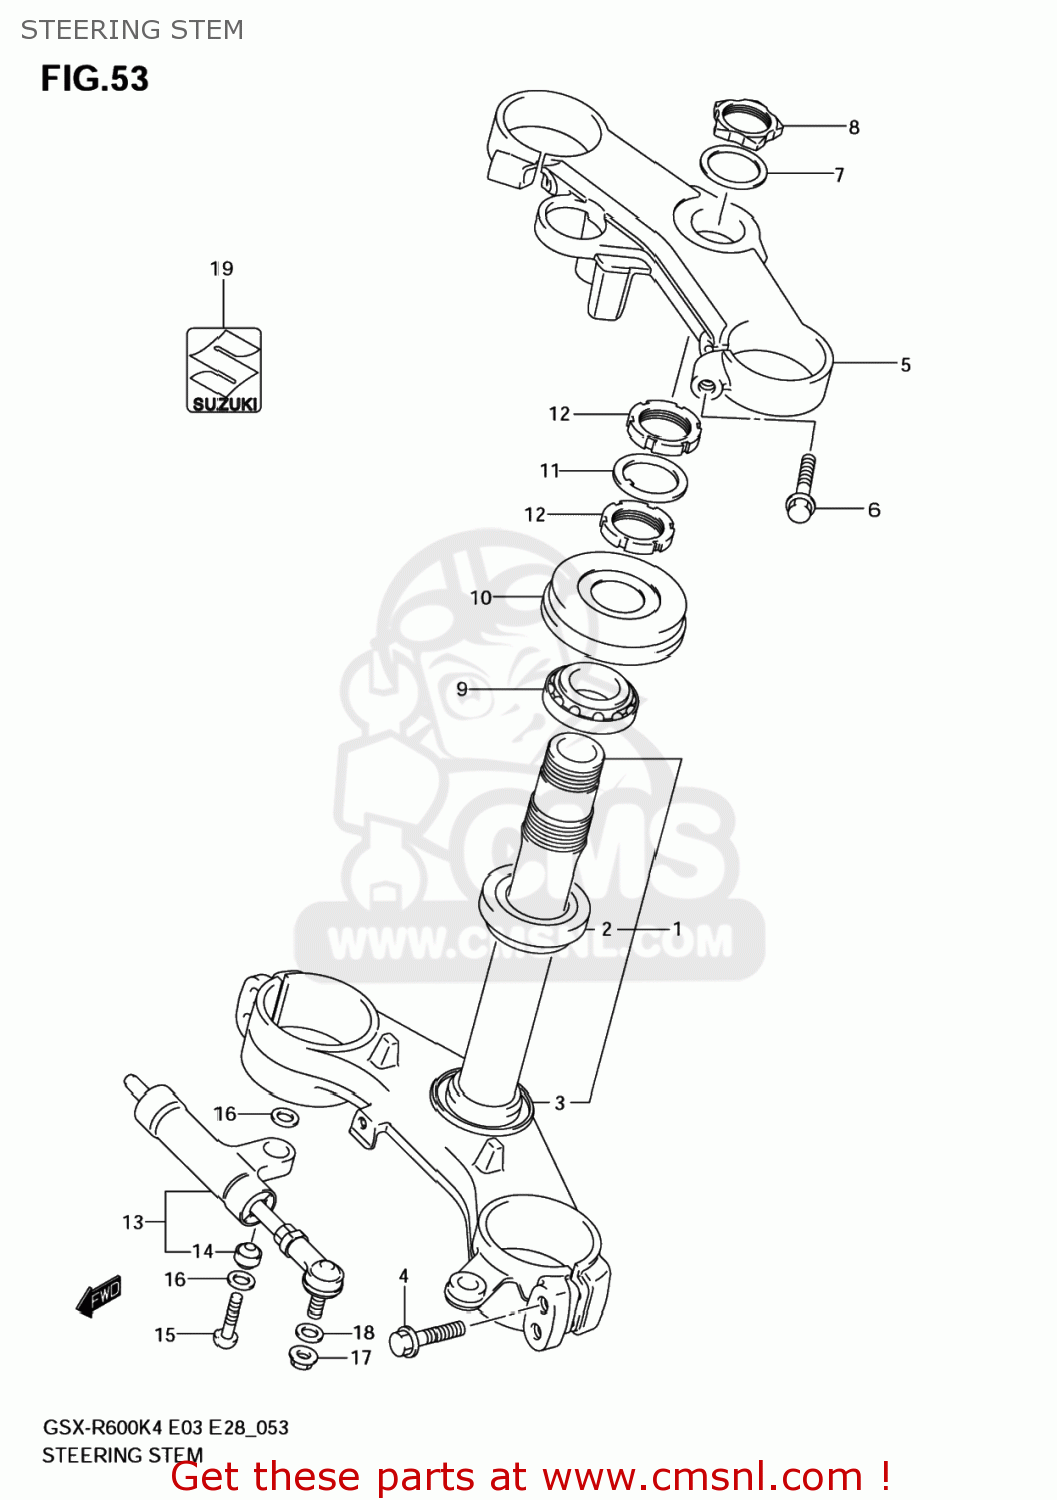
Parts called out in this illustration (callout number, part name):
1	STEM,STEERING
2	BEARING(30X55X17)
3	SEAL,STEERING LWR
4	BOLT,HOLDER AXLE(8X40)
5	HEAD,STEERING STEM
6	BOLT
7	WASHER
8	NUT,STEM HEAD
9	BEARING(30X55X17)
10	SEAL,STEERING UPR DUST
11	WASHER,STEERING STEM
12	NUT,STEERING STEM
13	DAMPER ASSY,STEERING
14	BEARING(8X17.5X11)
15	BOLT(8X35)
16	SEAL,PILLOW BALL,DUST
17	NUT
18	WASHER(8.5X18X1.6)
19	EMBLEM,S
